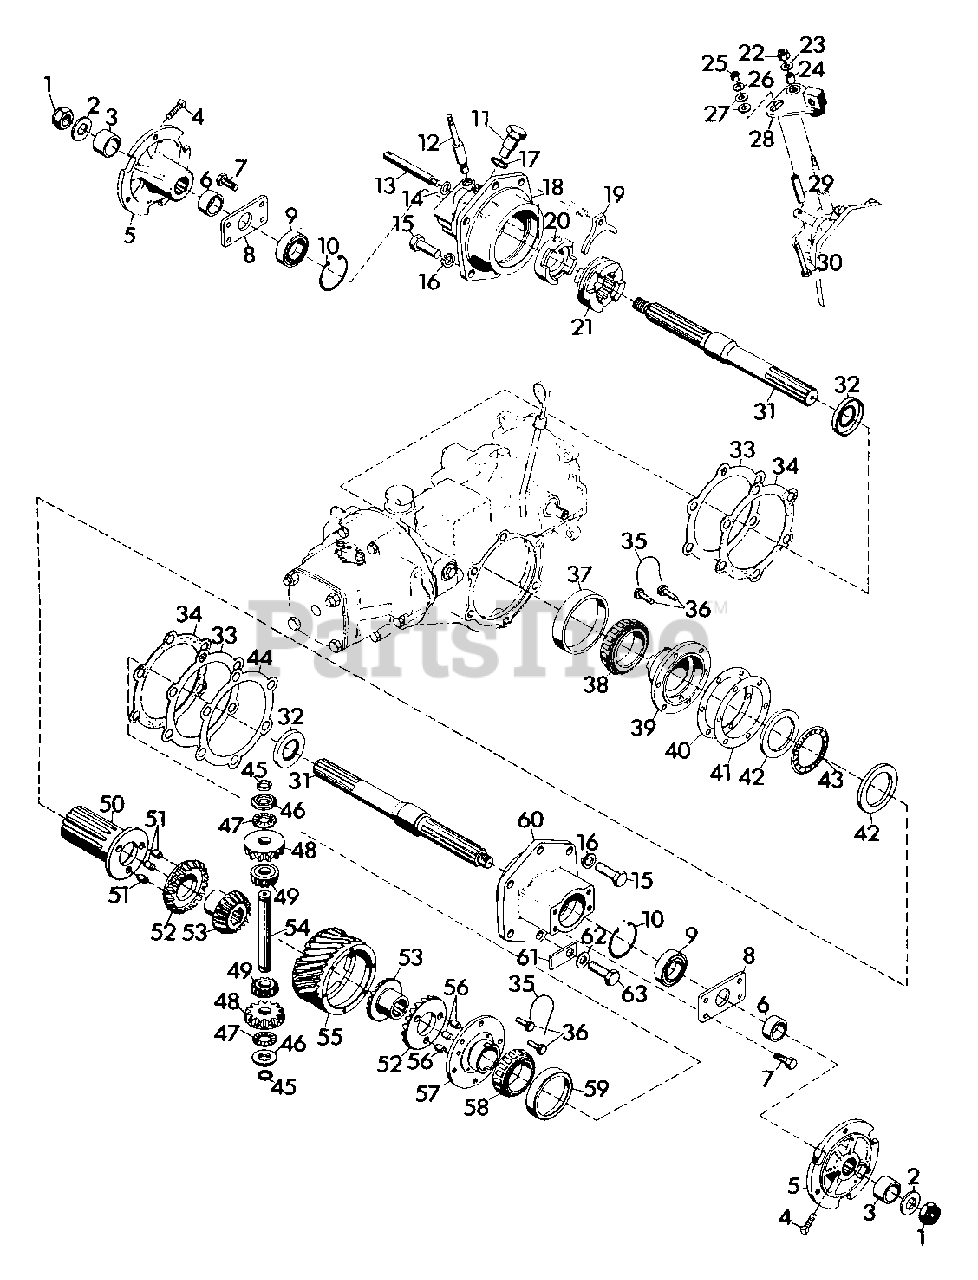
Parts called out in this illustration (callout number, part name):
1	Nut, Hex 3/4-10 Light Thin
2	Washer, Flat .812x1.469x.134
3	Spacer
4	Screw, Set 7/16-14x1.00 SQHCP
5	Hub, Wheel
6	Spacer
7	Bolt, Hex 3/8-16x.750
8	Plate, End
9	Bearing, Ball 1.000x2.000x.562
10	Ring, Retaining 2.000 Bore
11	Bolt, Stationary Clutch
12	Pivot, Stationary
13	Pin, Clutch Sliding
14	O-Ring .438x.625x.094
15	Bolt, Hex 1/2-13x1.000
16	Washer, Lock 1/2 Reg.
17	Washer, Oil Strainer Nut
18	Housing, Axle 2-Speed
19	Yoke, Shifting
20	Clutch, Stationary
21	Clutch, Shifting
22	Nut, Lock 5/16-18
23	Washer, Flat .344x.688x.065
24	Bushing, Nylon .375x.503x.875
25	Nut, Lock 1/4-20
26	Washer, Flat .281x.625x.065
27	Washer, Flat .406x.812x.065
28	Weldment, Arm Shifter
29	Bushing
30	Bolt, 1/4-20x2.25 Gr. 8 PHd
31	Axle, Straight
32	Seal, Oil 1.188x2.000x.250
33	Shim, Axle Housing .020
34	Gasket, Axle Housing
36	Bolt, Special 5/16-18
37	Cup, Roller Bearing
38	Cone, Roller Bearing
39	Housing, Clutch
40	Shim, Clutch Worm Gear .020
41	Shim, Clutch Worm Gear .005
42	Race, Thrust 2.002x2.740x.031
43	Bearing, Needle Thrust .060
44	Shim, Axle Housing .005
45	Ring, Retaining .750 Shaft
46	Spacer, .765x1.245x.200
47	Bearing, Needle Thrust .752x1.240x.078
48	Gear, Differential Shifting Bevel
49	Gear, Spider Bevel
50	Shifter, Splined Pinned
51	Pin, Dowel .375x.375
52	Gear, Pinned Bevel
53	Gear, Differential Bevel
54	Pin, Spider
55	Gear, Worm 8 Start
55	Gear, Worm 6 Start
56	Pin, Dowel .375x.500
57	Housing, Pinned
58	Cone, Roller Bearing
59	Cup, Roller Bearing
60	Housing, Axle
61	Washer, Oil Drain
62	Washer, Flat .531x1.062x.095
63	Bolt, Hex 1/2-13x1 Nylon Insert
